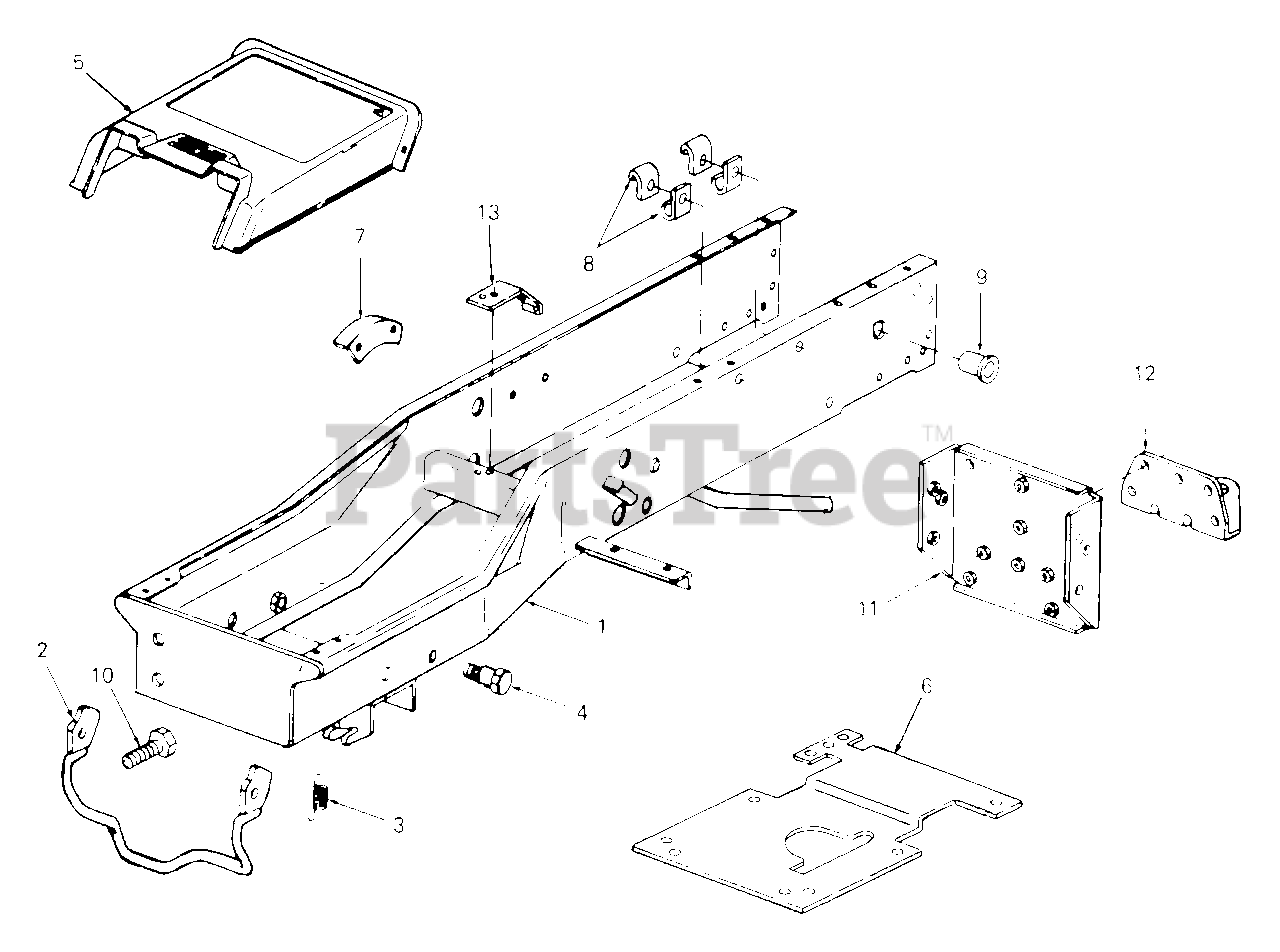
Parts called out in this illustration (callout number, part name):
3	Spring, Latch
4	Bolt, Shoulder
5	Cover, Frame
7	Bracket, Height Indicator
8	Clip, Cable
9	Bushing, Snap
10	Screw, Adjustment, 1/2-20 X 1.0 Lg GR5
13	Bracket, Switch
